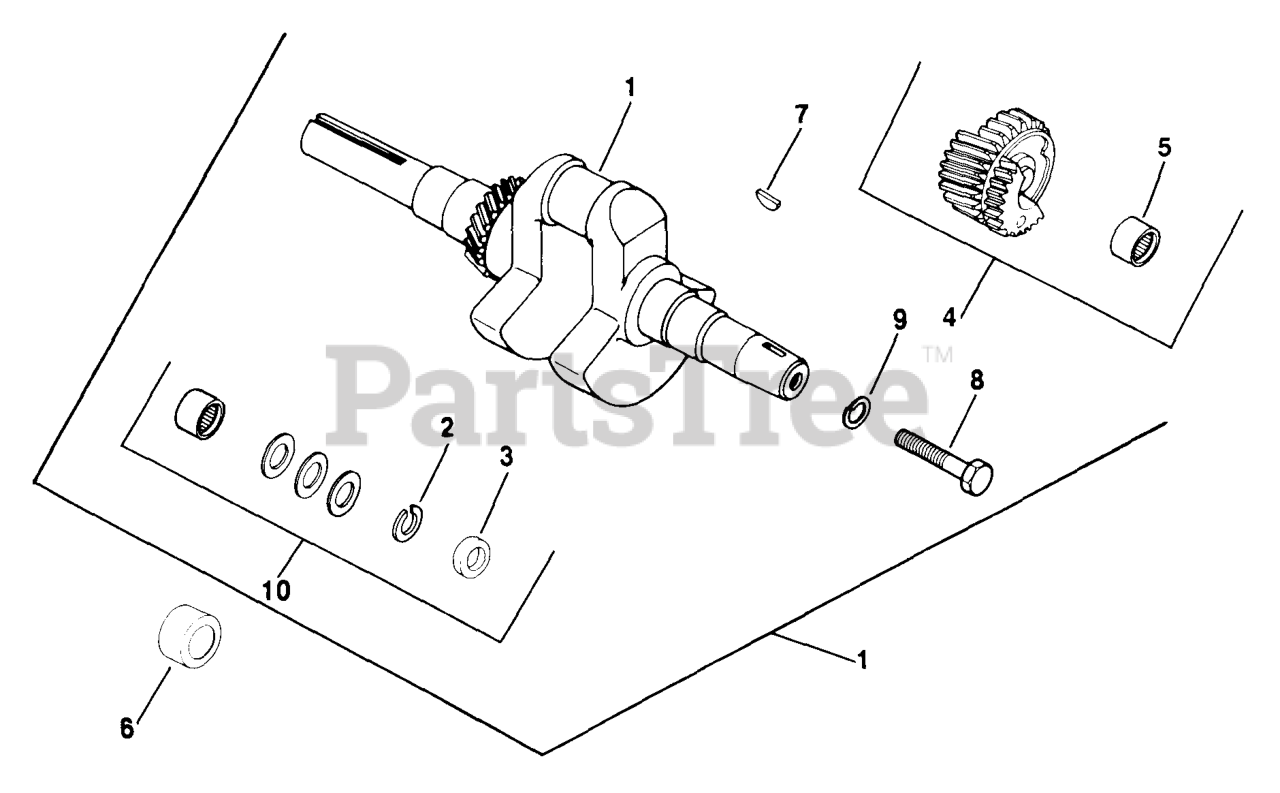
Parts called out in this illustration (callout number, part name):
1	CRANKSHAFT KIT - DISCONTINUED
7	KEY, 3/16" X 1"
8	SCREW, MACH 3/8-24X1-1/4"
9	WASHER (KM)-USE 12 468 03-S
